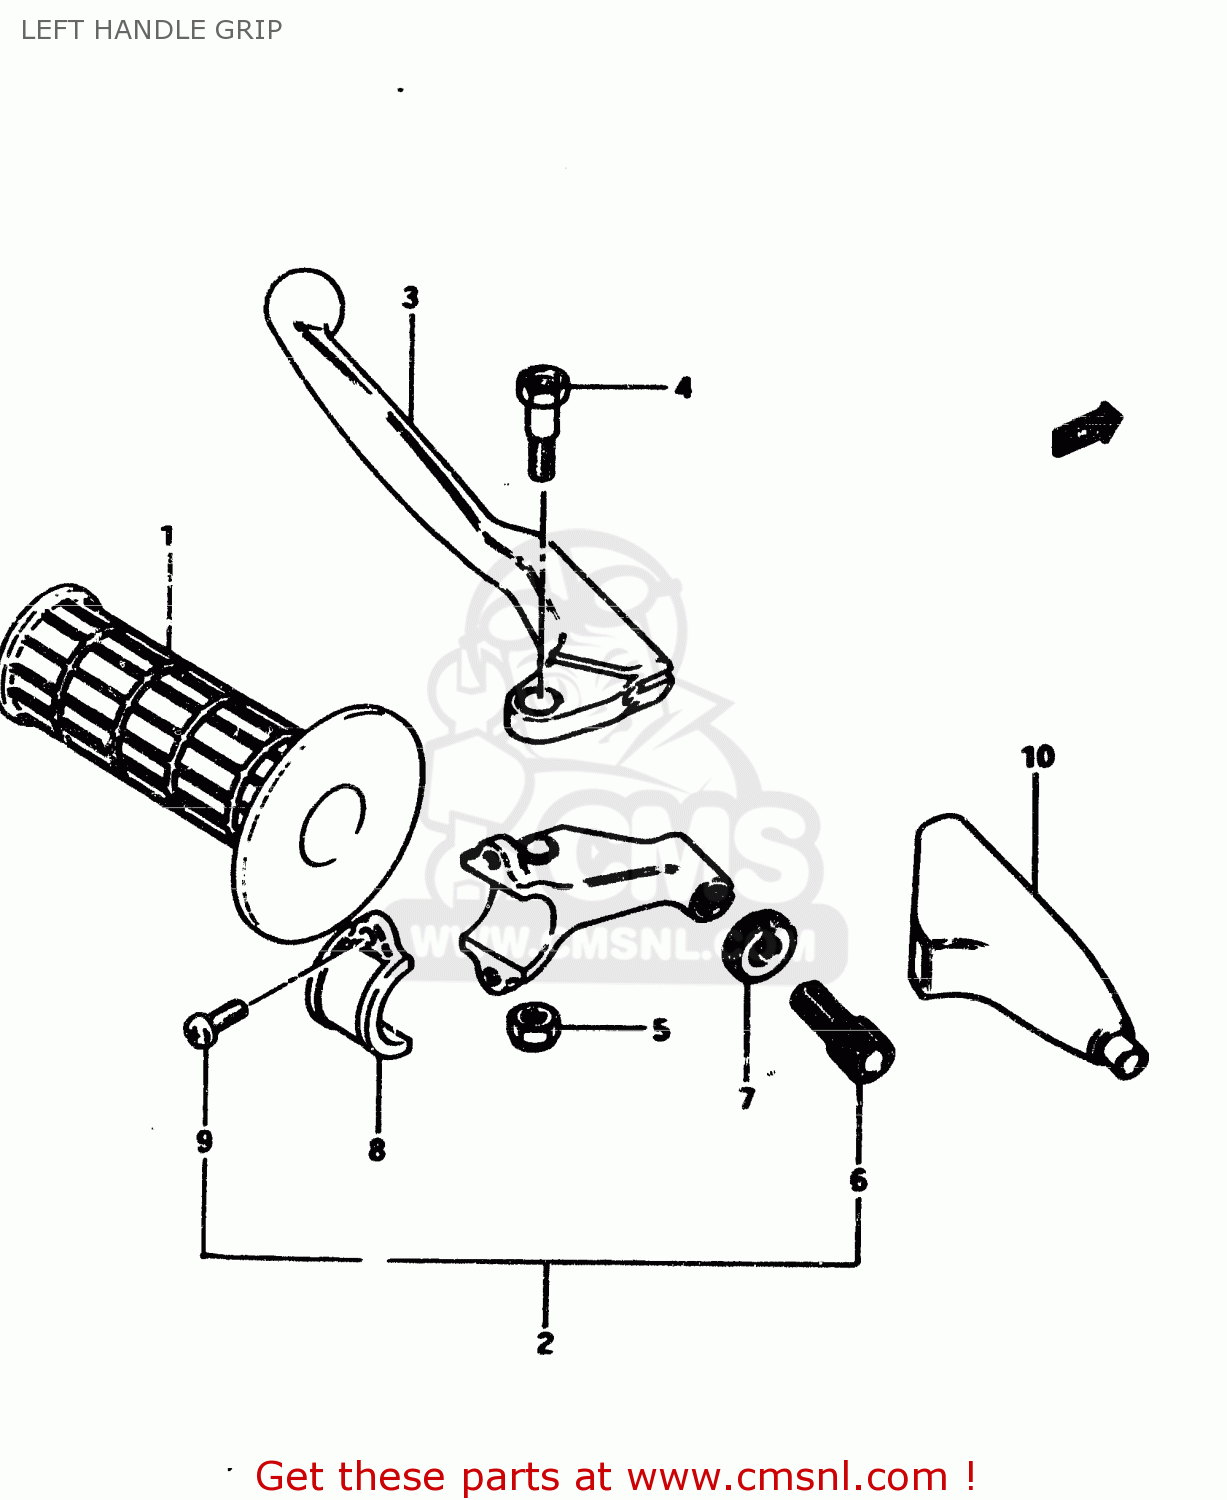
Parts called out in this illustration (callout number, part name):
1	GRIP,LEFT
2	LEVER ASSEMBLY
3	LEVER,CLUTCH
4	BOLT,LEVER
5	NUT
6	ADJUSTER,CABLE
7	NUT,CABLE ADJUSTER LOCK
8	HOLDER,LEVER
9	SCREW (5X14)
10	COVER,CLUTCH LEVER
